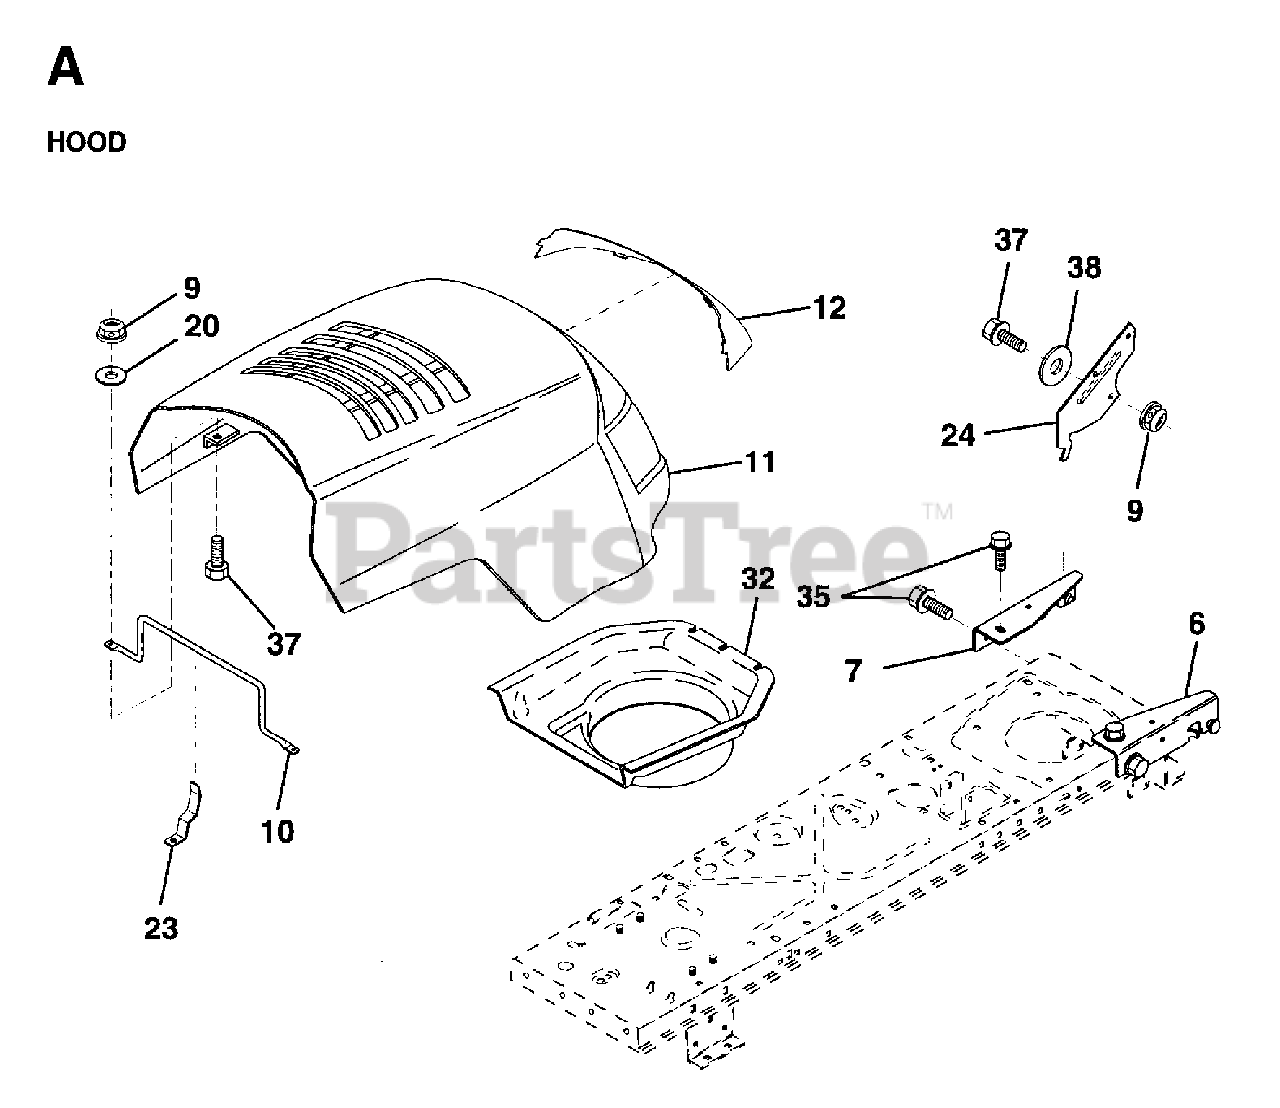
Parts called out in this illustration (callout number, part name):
6	BRACKET ASSY HOOD
7	BRACKET ASSY
9	LOCKNUT
20	WASHER
23	HOOD LATCH
35	SCREW
